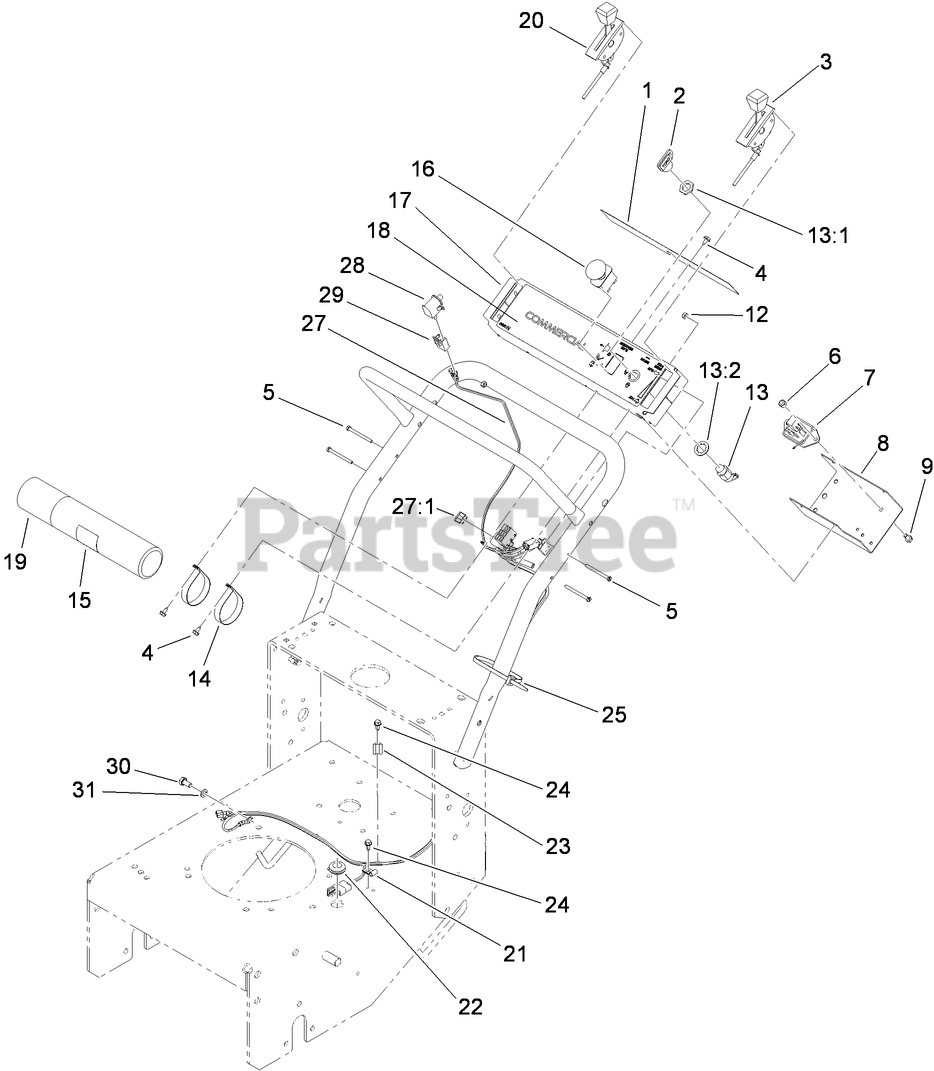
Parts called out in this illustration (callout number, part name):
1	DECAL-DANGER
2	KEY-IGNITION
3	CABLE-THROTTLE
4	SCREW-HWHTF
5	SCREW-SHH
6	NUT-LOCK, NI
7	MODULE-DELAY
8	PANEL-BOTTOM
9	SCREW-HH
12	NUT-LOCK, NI
13	SWITCH-ON / OFF
13:1	NUT-HH
13:2	WASHER-TOOTH, INTERNAL
14	CLAMP-R
15	TUBE-MANUAL
16	SWITCH-PTO
17	PANEL-CONTROL
18	DECAL-PANEL, CONTROL
19	CAP-HOUSING
20	CABLE-CHOKE
21	CLIP-CLOSED, INSULATED
22	GROMMET
23	CLAMP-R
24	SCREW
25	TIE-CABLE
27	HARNESS-WIRE
27:1	FUSE-BLADE, 7.5 AMP
28	SWITCH-BAIL
29	CONNECTOR-BODY
30	SCREW-HH
31	WASHER-LOCK
